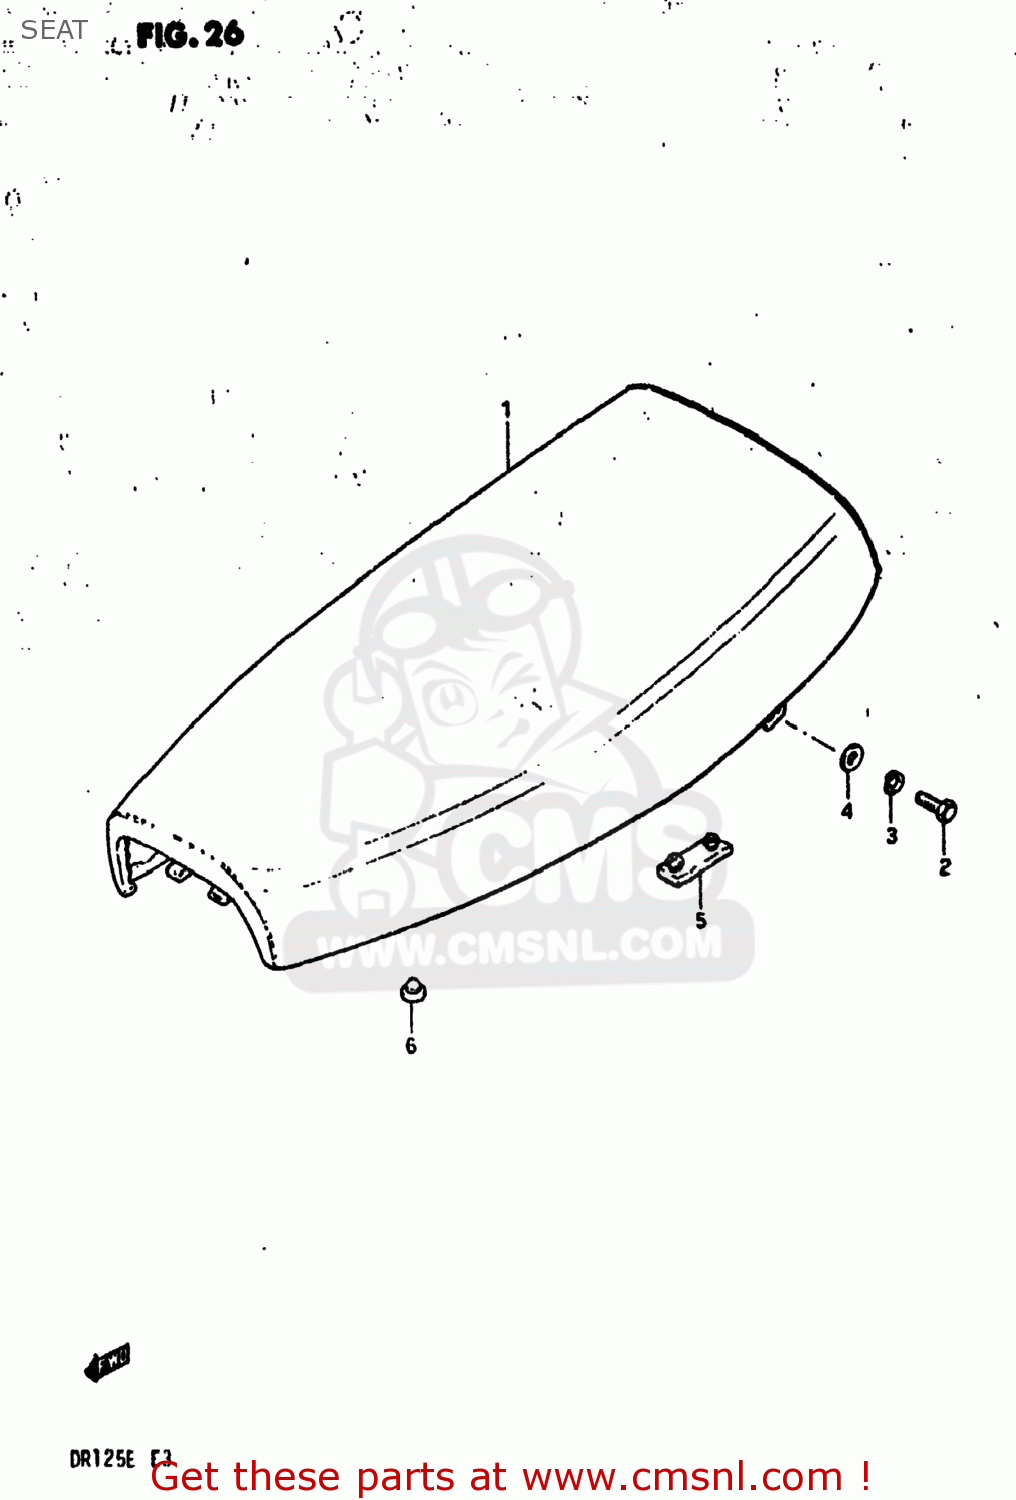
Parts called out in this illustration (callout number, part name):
1	SEAT ASSEMBLY
2	BOLT
3	LOCK WASHER
4	WASHER,8.5X16X
5	CUSHION
6	CUSHION
